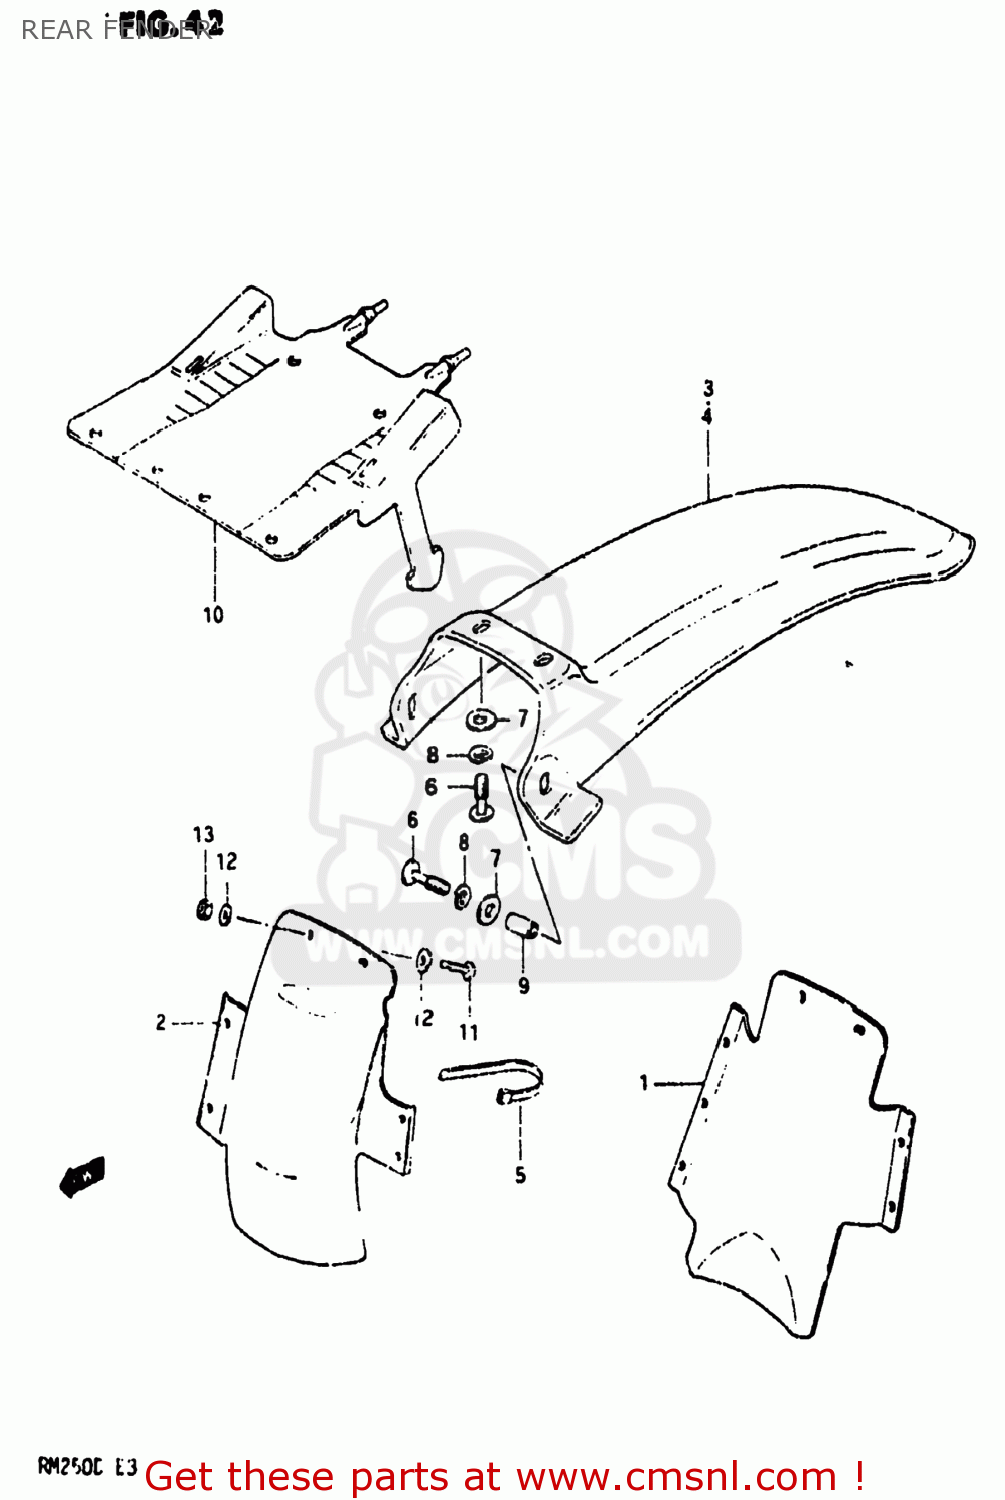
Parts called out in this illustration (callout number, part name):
1	FENDER,REAR
2	FENDER,REAR
3	FENDER,REAR
4	FENDER,REAR
5	CLAMP
6	SCREW
7	WASHER (6.5X20X1.2)
8	LOCK WASHER
9	SPACER
10	GUIDE,RR FENDER MUD
11	SCREW
12	WASHER
13	NUT
